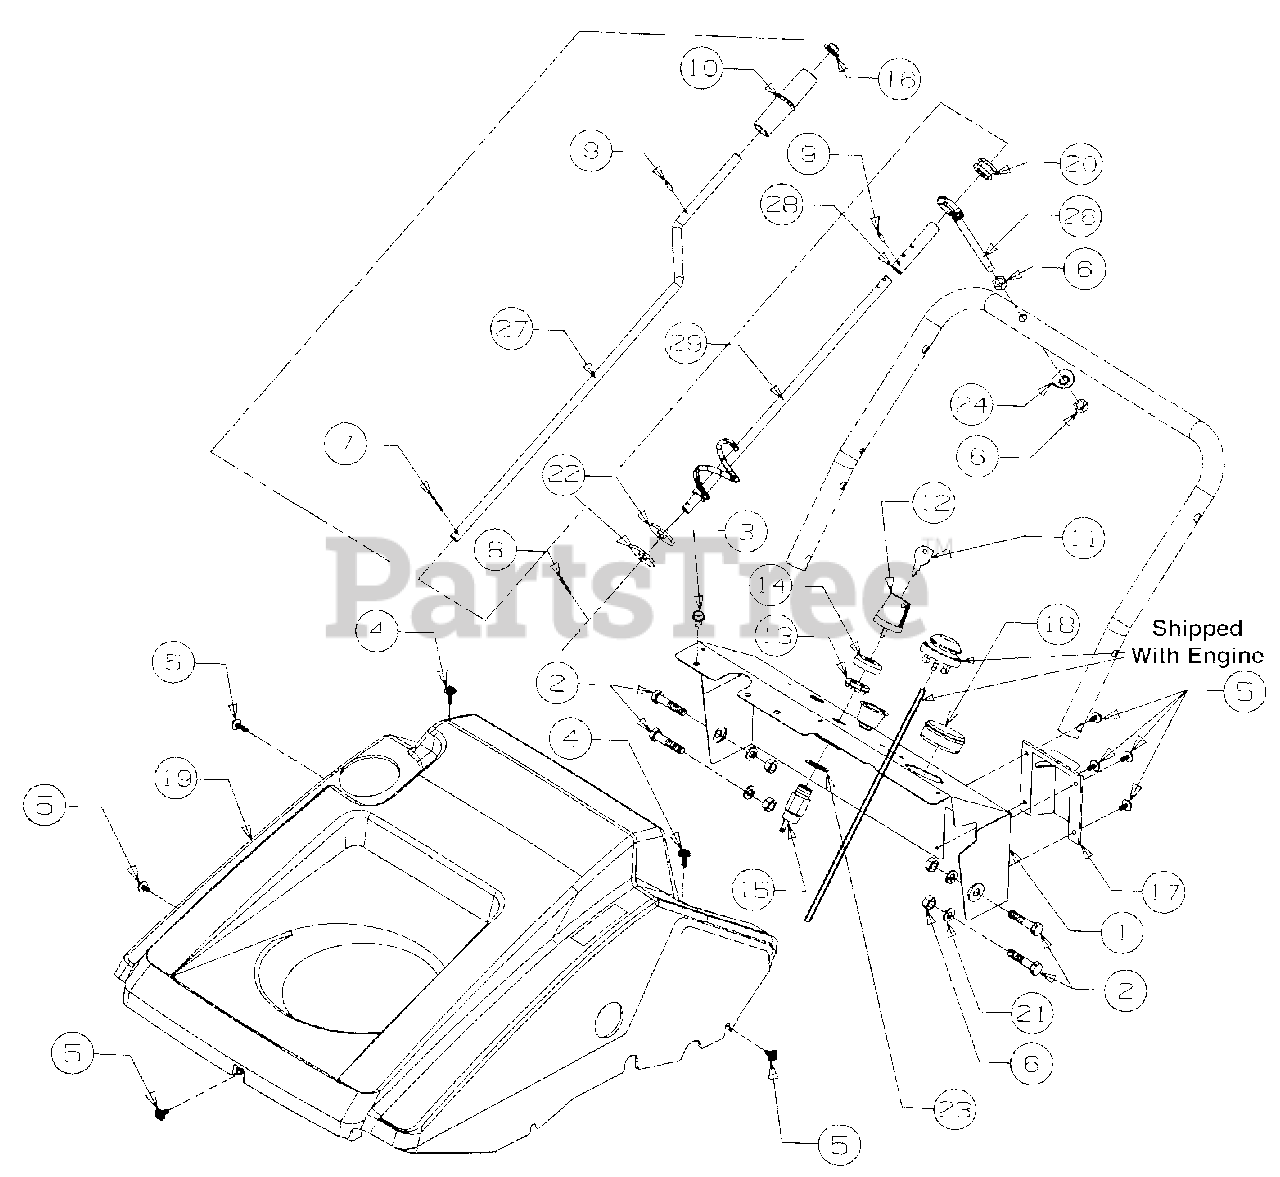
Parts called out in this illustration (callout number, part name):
3	Screw-Hex Washer
4	Screw-Hex
5	Screw-Hex
6	Nut-Hex
7	Pin-Cotter
8	Pin-Cotter
9	Pin-Roll
11	Key-Ignition
12	Key-Ignition with Logo
13	Nut-Ignition Switch
14	Cover-Ignition Switch
15	Switch-Key
16	Cap-Push
17	Cover-Choke
18	Plug-Insert
19	Shroud-Black
20	Grommet-Rubber
21	Washer-Lock
23	Washer-Lock Internal
24	Washer-Saddle
26	Eyebolt-Chute Crank
28	Spacer
